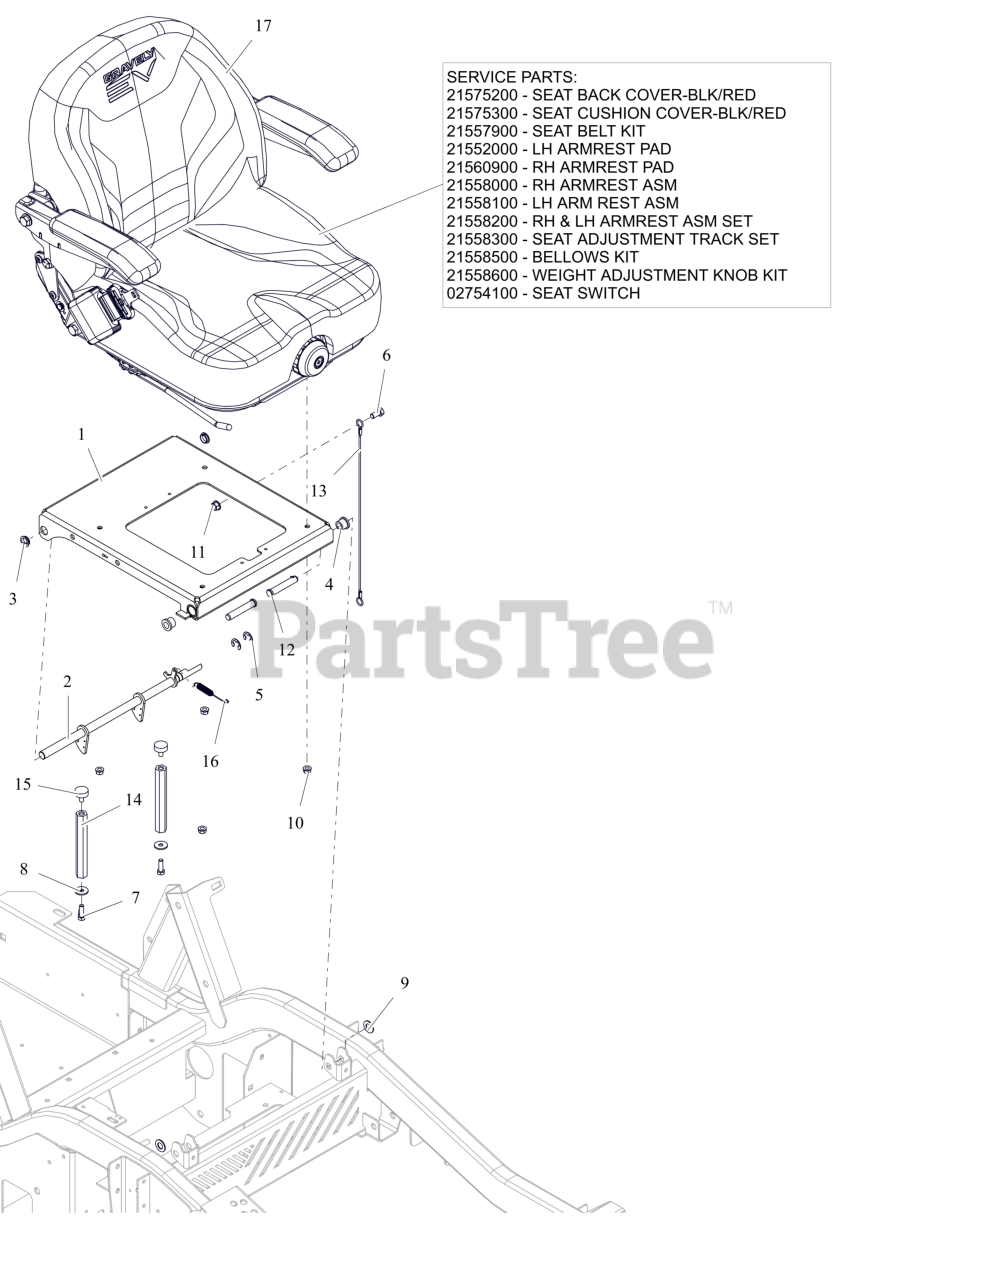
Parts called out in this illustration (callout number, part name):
1	WLDMT, SEAT PLATE (RED)
2	WLDMT, SEAT LATCH (RED)
3	BUSHING, POLYLINER-.63 SNAPIN
4	BSHG, FLG .516X.750X.625X.937
5	RG-RTNG-EXT .625X.042
6	BLT,HEX .38-16X.75 G5 ZCC
7	BLT, HEX .31-18X1.00 G8 ZCC M
8	WSHR,FLT .328X1.00X.094 ZCC
9	WSHR, FLT .531X1.00X.063 ZCC
10	NUT,LK-CTR-FLG .31-18 GF ZCC
11	NUT-LK-CTR-FLG .375-16 GF ZCC
12	PIN, SLIC-.500X42.70X2.31 -ZC
13	CABLE, WIRE (LANYARD)-.093X16.20
14	NUT, COUPLING .312-18 X 5.715
15	BUMPER, RUBBER
16	SG-TENS .043X.44X3.31 WLD 5.8
17	SEAT, GRAVELY MECH SUSPENSION LVR
17	SEAT BACK COVER-BLK/RED
17	SEAT CUSHION COVER-BLK/RED
17	KIT, SEAT BELT
17	PAD, ARMREST (HARD)
17	ARMREST, RH ASSEMBLY
17	ARMREST, LH ASSEMBLY
17	SET, RH & LH ARMREST ASSEMBLY
17	SET, SEAT ADJUSTMENT TRACK
17	KIT, BELLOWS
17	KIT, WEIGHT ADJUSTMENT KNOB
17	SWITCH- SNAP MTG N.O.
